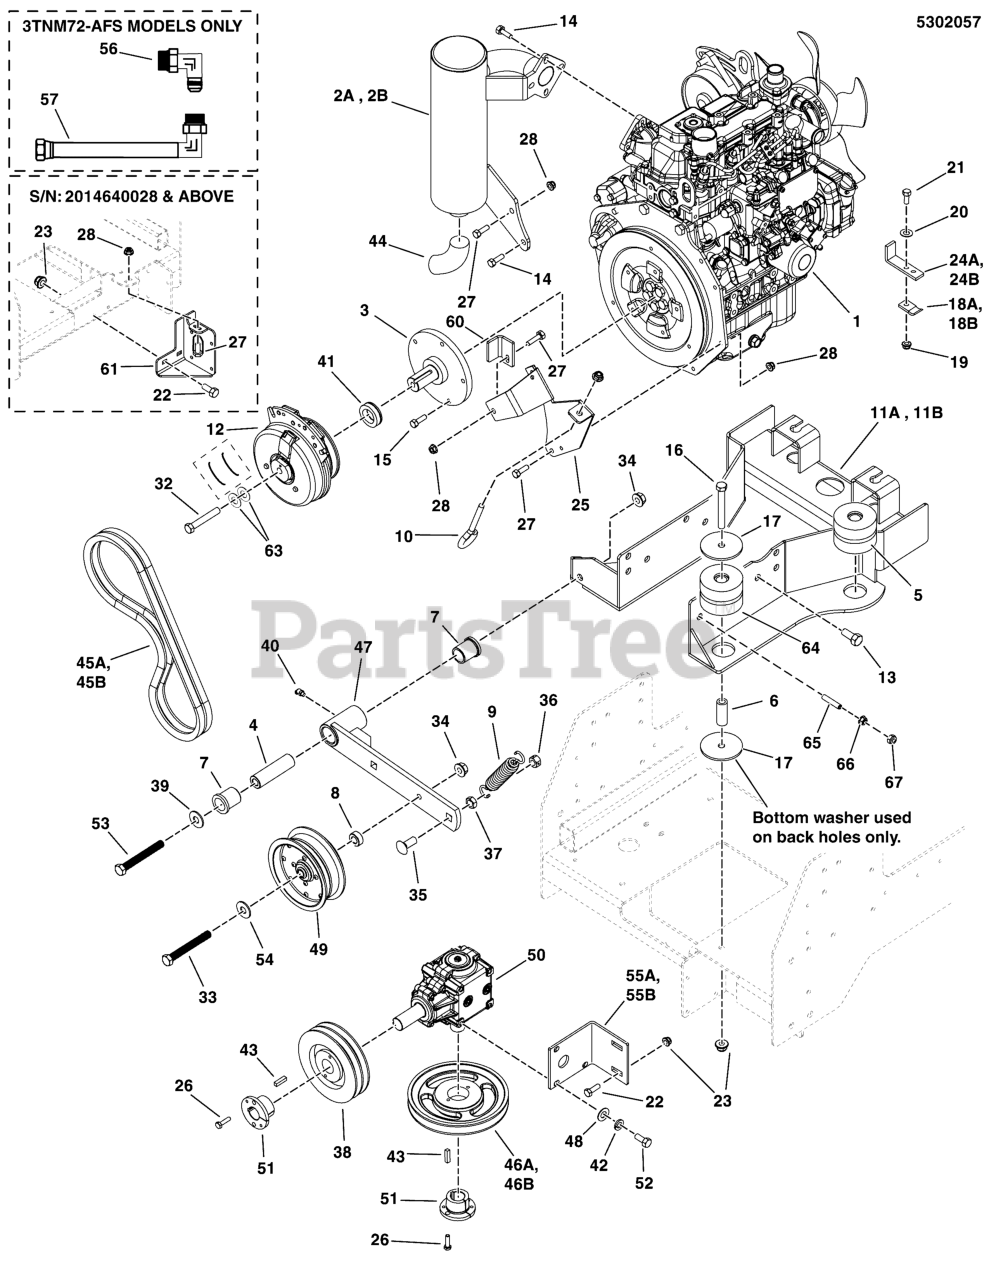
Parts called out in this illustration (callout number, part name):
1	ENGINE, YANMAR
3	SHAFT, STUB, YANMAR, FLYWHEEL PLATE
4	SPACER, .52 X 1.00 X 3.50
5	ISO-MOUNT, REAR
6	SPACER, .38 X .62 X 1.62
7	BUSHING, FLANGE
8	SPACER, .39 X .75 X .38
9	SPRING-EXT 1.03OD X 6.935LG X .120WR BLK
10	EYE BOLT, 3/8-16 X 6.88, 3THRD, 1EYE
12	CLUTCH, WARNER ELECTRIC,
13	BOLT, M10-1.5 X 16MM GD8.8
14	BOLT, M8-1.25 X 20MM GD8.8
15	BOLT, M8-1.25 X 25MM GD8.8
16	BOLT, 3/8-16 X 3" GD5 CZ
17	WASHER, .39 X 2.50 X .125
19	NUT, #10-24 HEX NYLON LOCK
20	WASHER, #10 SAE
21	SCREW, #10-24 X 1 RS, CZ
22	BOLT, Carriage, 3/8-16 X 1
23	NUT, 3/8-16 HEX NYLOCK FLANGE
25	ANCHOR, CLUTCH - RED
26	BOLT, 1/4-20 X 1" GD5 CZ
27	BOLT, 5/16-18 X 1 GD5 YZ
28	NUT, 5/16-18 HEX NYLOCK FLANGE
29	NUT, M8-1.25 SERR. FLANGE, CZ
30	BOLT, 5/16-18 X 2 GD5 TFL
31	NUT, 5/16-18 HEX SERRATED FLANGE (SMALL)
32	BOLT, CRANKSHAFT, 7/16X2-3/4
33	BOLT, 1/2-13 X 3-1/4, HEX HD, GD5, CZ (SV)
34	NUT, Hex Flange, Nylock, 1/2-13
35	BOLT, CARRIAGE 1/2-13 X 1-1/4 GD.5
36	NUT, 1/2-13 HEX SIDE LOCK
37	NUT, 1/2-13 HEX JAM
38	PULLEY, 5.75 OD X 2 GROOVE, SPECIAL
39	WASHER, 1/2 USS
40	GREASE FITTING, 45 DEGREE
41	SPACER, 1.13 X 1.75 X .50
42	WASHER, 5/16 LOCK CZ
43	KEY, 1/4 SQ X 1
44	TAIL PIPE, 1-1/2", 90 DEGREE (SV)
47	WELD, IDLER ARM - RED
48	WASHER, 5/16" SAE
49	PULLEY, IDLER, DOUBLE FLGED, 4IN
50	GEARBOX, RIGHT ANGLE, 1:1
51	BUSHING, TAPERED HUB
52	BOLT, 5/16-18 X 3/4 GD5
53	BOLT, 1/2-13 X 4-1/2 GD5
54	WASHER, 1/2 SAE
56	FITTING, #8JIC, ELBOW
57	HOSE, OIL DRAIN
60	BRACKET, CLUTCH ANCHOR, IS2500 - BLK
61	WELD, GEAR BOX
63	BELLEVILLE WASHER 1.1875 X .442 X .089
64	ISO MOUNT, 490 LBS, GREEN
65	SOCKET SET SCREW, M10-1.5 X 50, SS, CAP PT
66	HEX NUT, FLG, M10-1.5 SER CZ, NO SEALER
67	NUT, M10-1.5, NYLON INSERT
